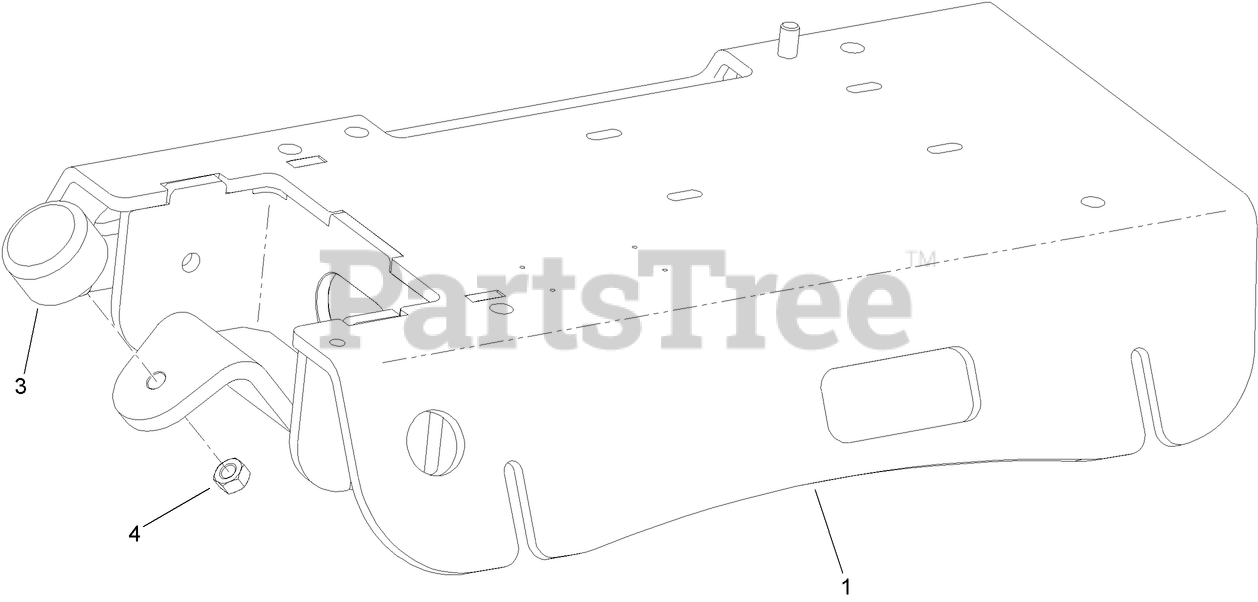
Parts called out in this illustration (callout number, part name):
1	PLATE-ENGINE
3	BUMPER-RUBBER
4	NUT-LOCK, NI
